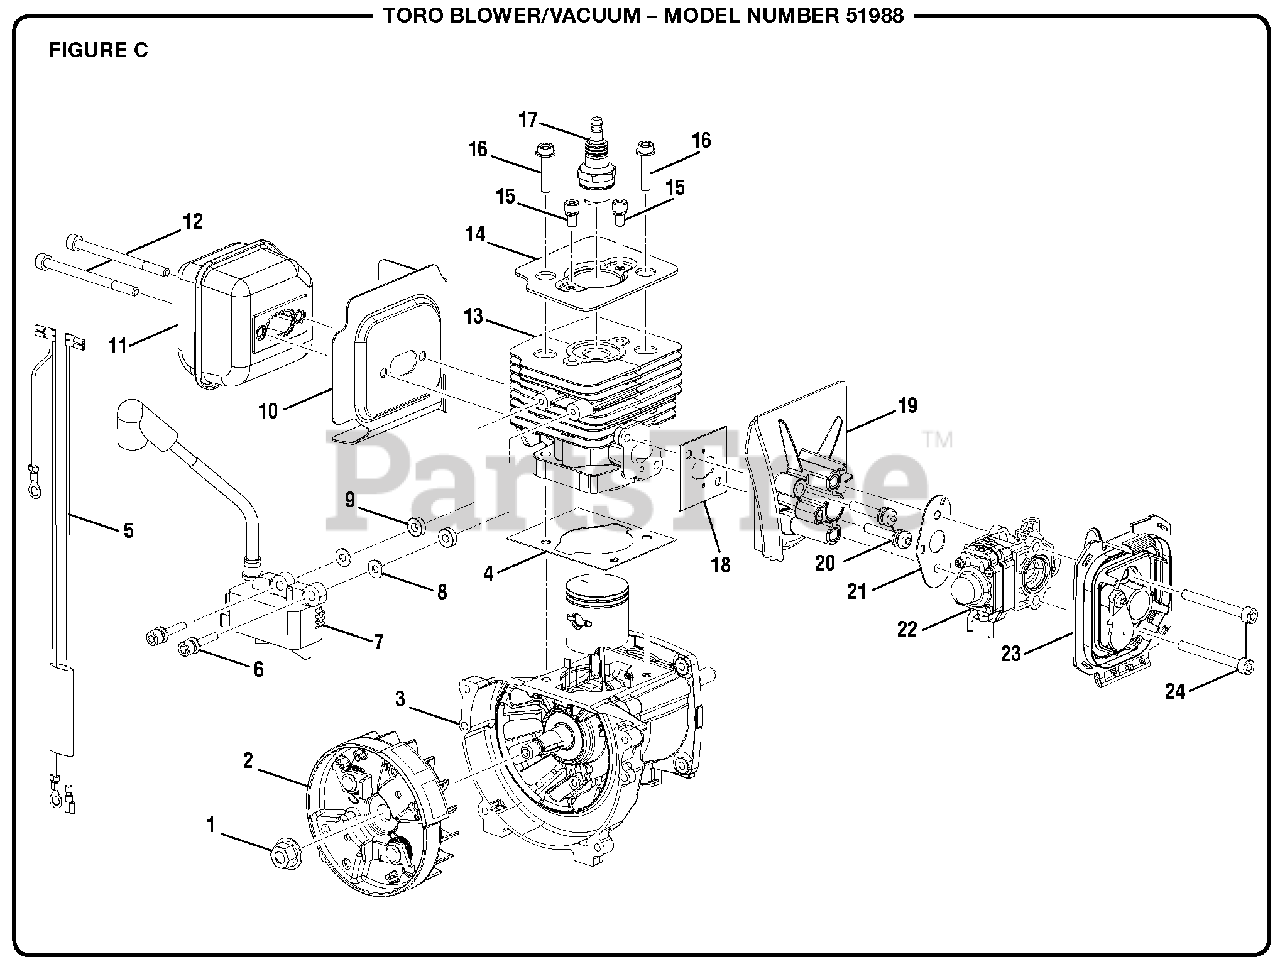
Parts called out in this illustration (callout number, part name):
1	Nut (M8)
2	Flywheel Assembly
3	Crankcase and Piston Assembly
5	Wire Harness
6	Screw (M4 x 22 mm)
7	Ignition Module
8	Washer (42ID x 10OD x ?t)
10	Muffler Gasket
11	Muffler Assembly
12	Screw (M5 x 65 mm, Torx T25)
14	Cylinder Plate
15	Screw w/Washer (M5 x 10 mm)
16	Screw (M5 x 22 mm)
17	Spark Plug (RCJ6Y)
18	Cylinder Gasket
19	Heat Sink
20	Screw (M5 x 27 mm, Torx T20)
21	Carburetor Gasket
22	Carburetor Assembly
23	Air Box Cover Base Assembly
24	Screw (M5 x 45 mm, Torx T25)
